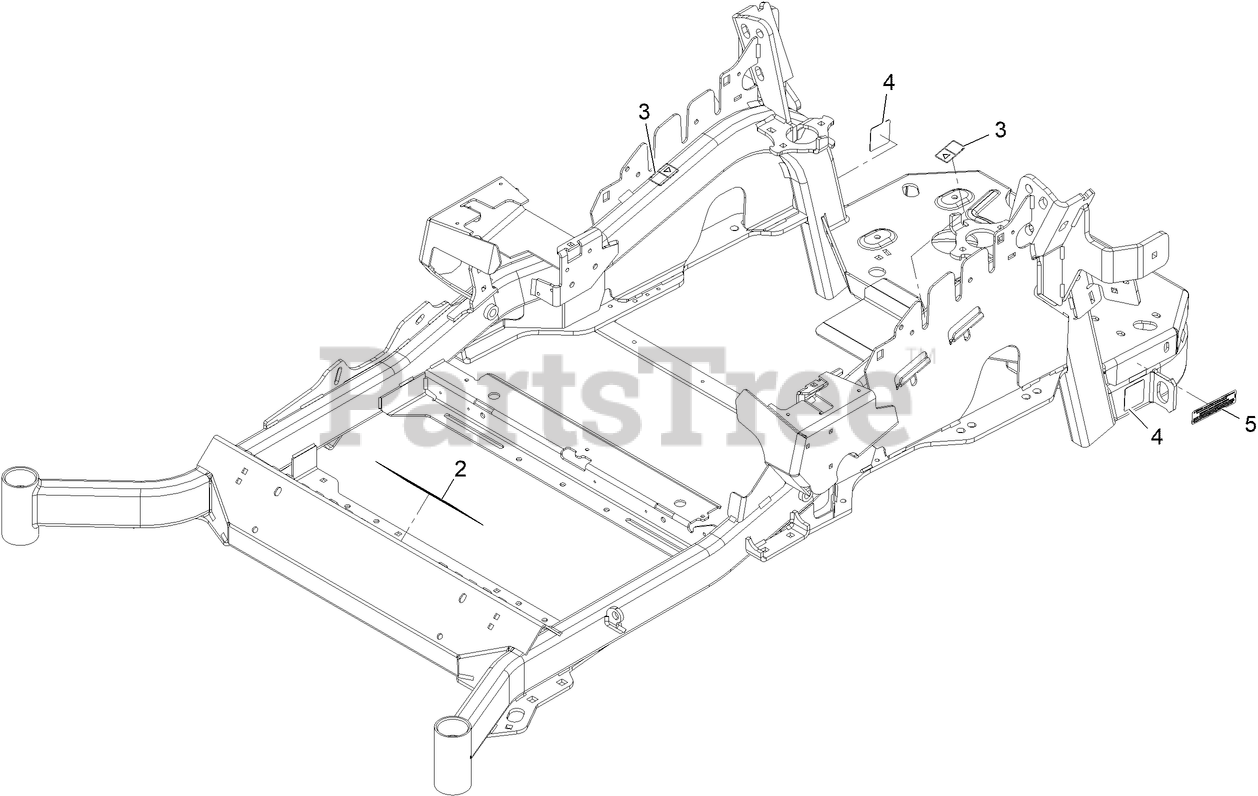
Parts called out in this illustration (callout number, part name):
2	DECAL-DANGER
3	DECAL-WARNING
4	DECAL-HAZARD, PINCHED FINGER
5	DECAL-ARRESTOR, SPARK
